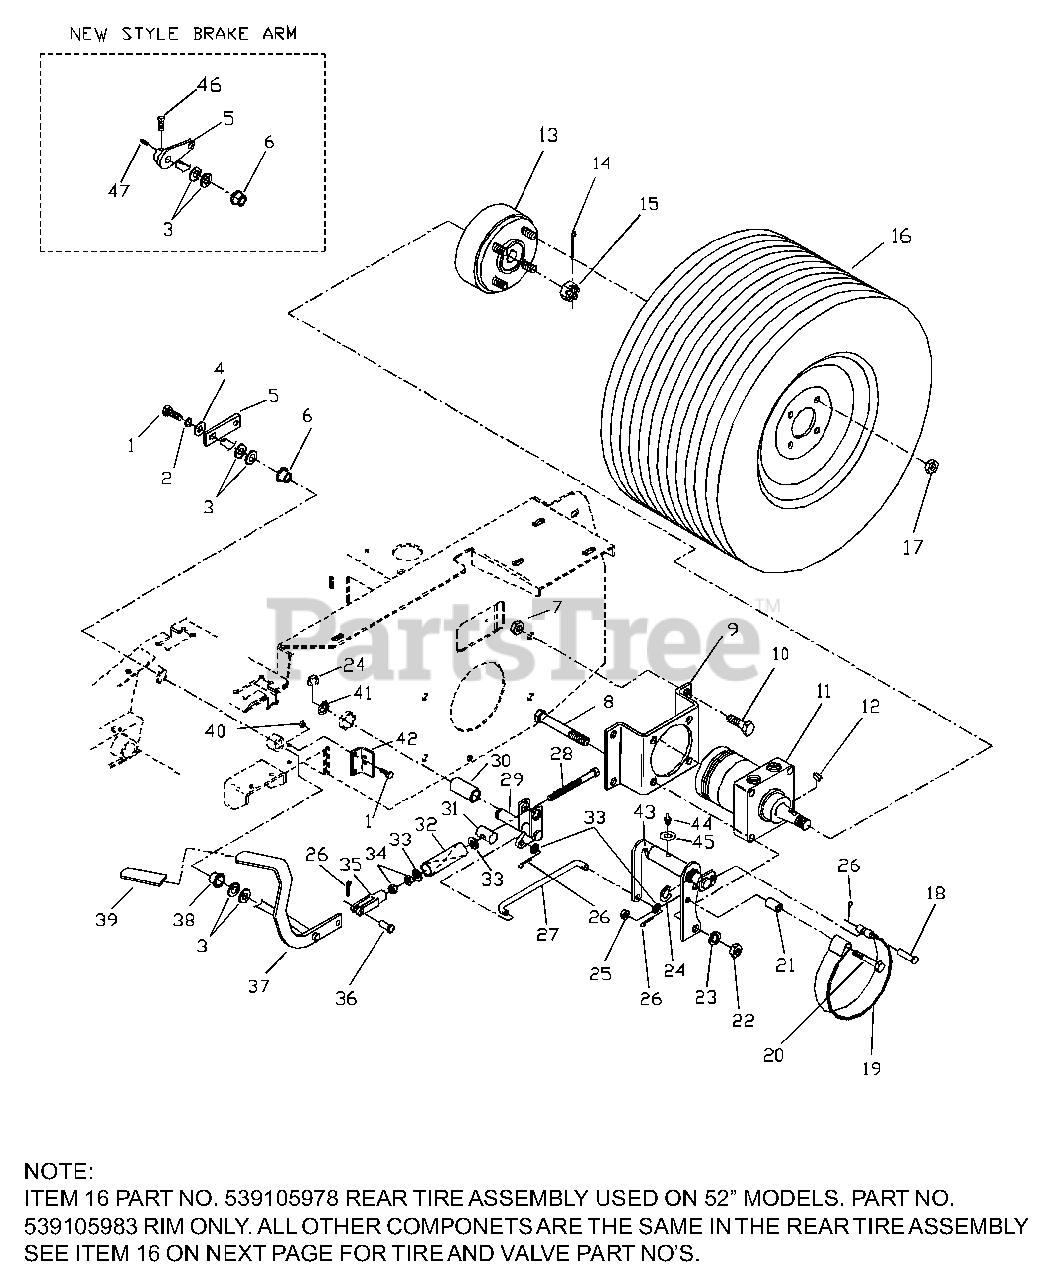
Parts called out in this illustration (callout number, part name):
1	HCS 1/4C X 3/4
2	1/4 LOCK WASHER
3	WASHER 7/16 SPRING
4	1/4 FLAT WASHER
5	ARM, PARK BRAKE
5	ARM, PARK BRAKE (NEW STYLE)
7	NUT 1/2C NYLOC
8	HCS 1/2C X 2.75
9	MOTOR STANDOFF
10	HCS 1/2C X 1.25
11	WHEEL MOTOR
12	WOODRUFF KEY
13	HUB W/ BRAKE DRUM
14	COTTER PIN
15	CASTLE NUT
16	REAR TIRE ASM OFFSET RIM (61" & 72" MODELS)
17	LUG NUT 1/2F
18	3/8 X 1.50 CLEVIS PIN
19	BRAKE BAND
20	HCS 3/8C X 3 GD 8
23	1/2 LOCK WASHER
24	E - RING 3/4
25	NUT 3/8C CTR. LOCK
26	COTTER PIN
27	BRAKE LINKAGE LT.
27	BRAKE LINKAGE RT.
28	HCS 3/8F SPECIAL
30	BRONZE BEARING
31	TRUNION PIN
33	3/8 SAE WASHER
36	3/8 X 1.125
37	BRAKE LEVER WLDMT.
37	BRAKE ARM WLDMT (NEW STYLE)
40	1/4C LOCK NUT
41	MACH. BUSHING 3/4
43	LEFT BRAKE BKT.
43	RIGHT BRAKE BKT.
44	ZERK
46	SETSCRW. 5/16 X .625
47	KEY 1/4 X .875
